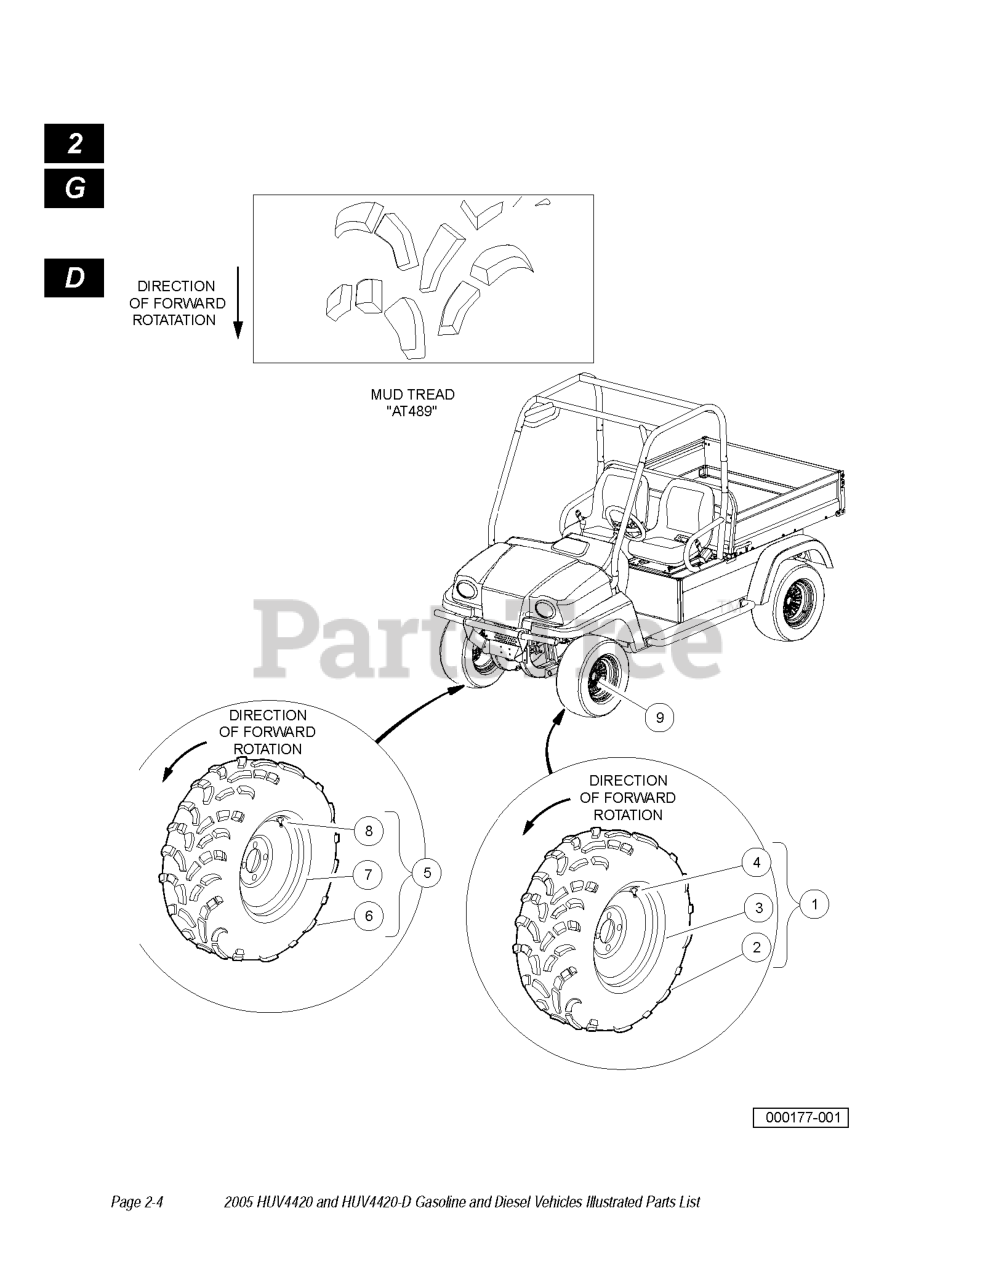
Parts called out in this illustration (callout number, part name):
1	Gray Tire Assembly, AT489 LH
2	TIRE, AT 489
3	Wheel, Indus Spider, Gray
5	Gray Tire Assembly, AT489 RH
6	TIRE, AT 489
7	Wheel, Indus Spider, Gray
9	NUT, LUG 1/2-20, SAE J 2283
